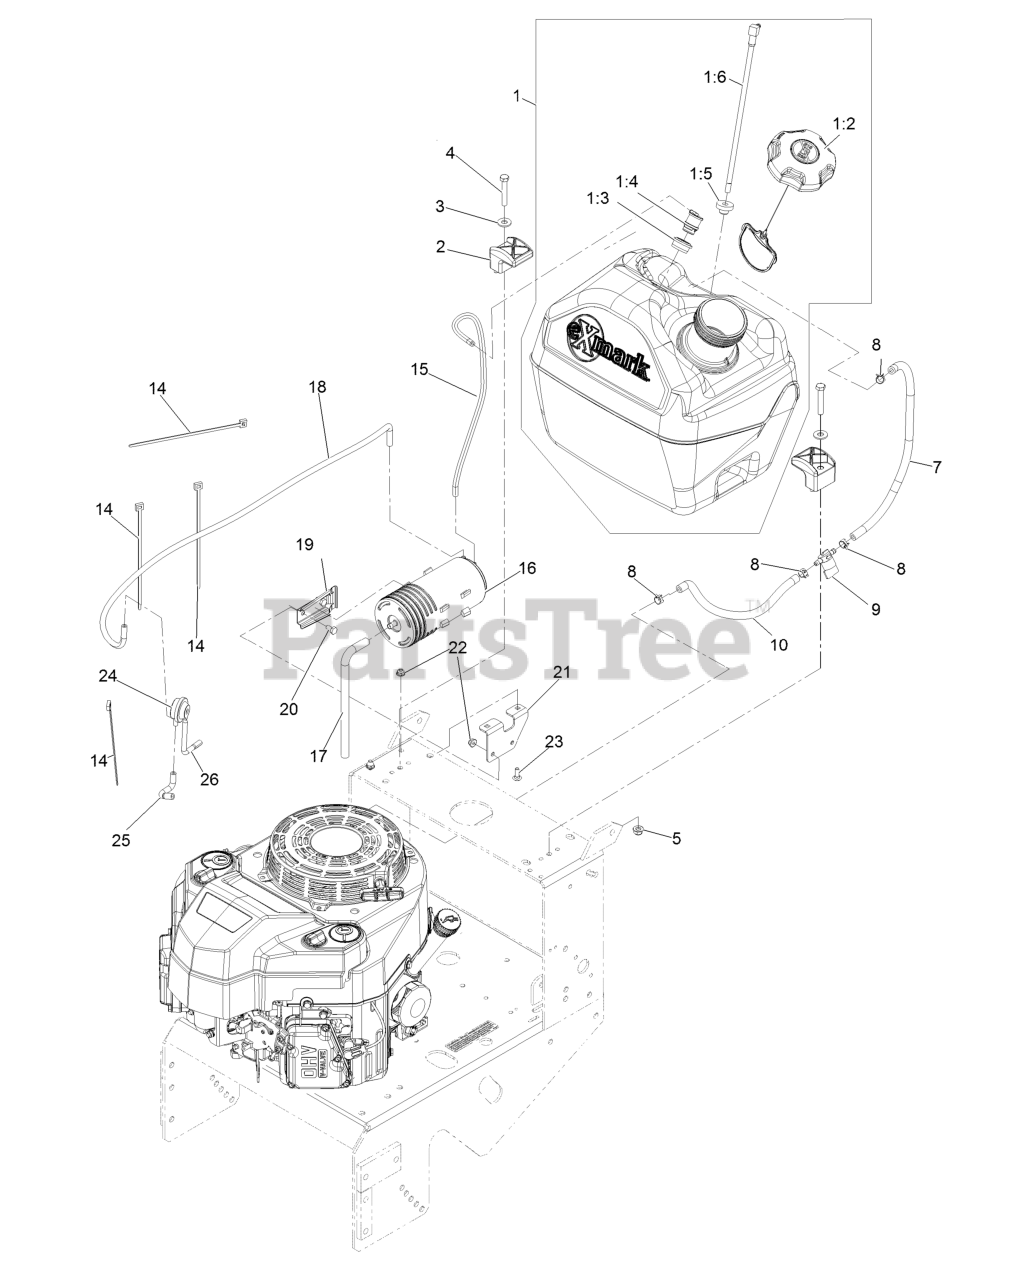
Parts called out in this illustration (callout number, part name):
1	ASM, Fuel Tank 5 Gal
1:2	Cap-Fuel, Ratcheting
1:3	Grommet
1:4	Valve-Vent, Fuel
1:5	Bushing
1:6	Fitting-Fuel (W/Line And Screen)
3	Washer-5/16 Std
4	Screw-HH 5/16-18 X 2
5	Nut-Nyloc 5/16-18 Flg
7	Hose-Fuel
8	Clamp-Hose
9	Valve-Fuel
10	Hose-Fuel Line 8 1/2"
14	Tie-Cable 7 15/16 (Large)
15	Hose-Vent
16	Canister-Carbon, 800Cc
17	Hose-Vent, Canister
18	Hose-Vent, Formed
19	Bracket-Canister, Carbon
20	Screw-HH 1/4-20 X 1/2
21	Bracket-Canister, Carbon
22	Nut-Nyloc 1/4-20 Flg
23	Bolt-Carriage 1/4-20 X 3/4
24	Valve-Control, Vacuum
25	Hose-Vent, Formed
26	Hose-Vent, Formed
28	Pn 41019-1055 Filter W/6In Fuel Line
